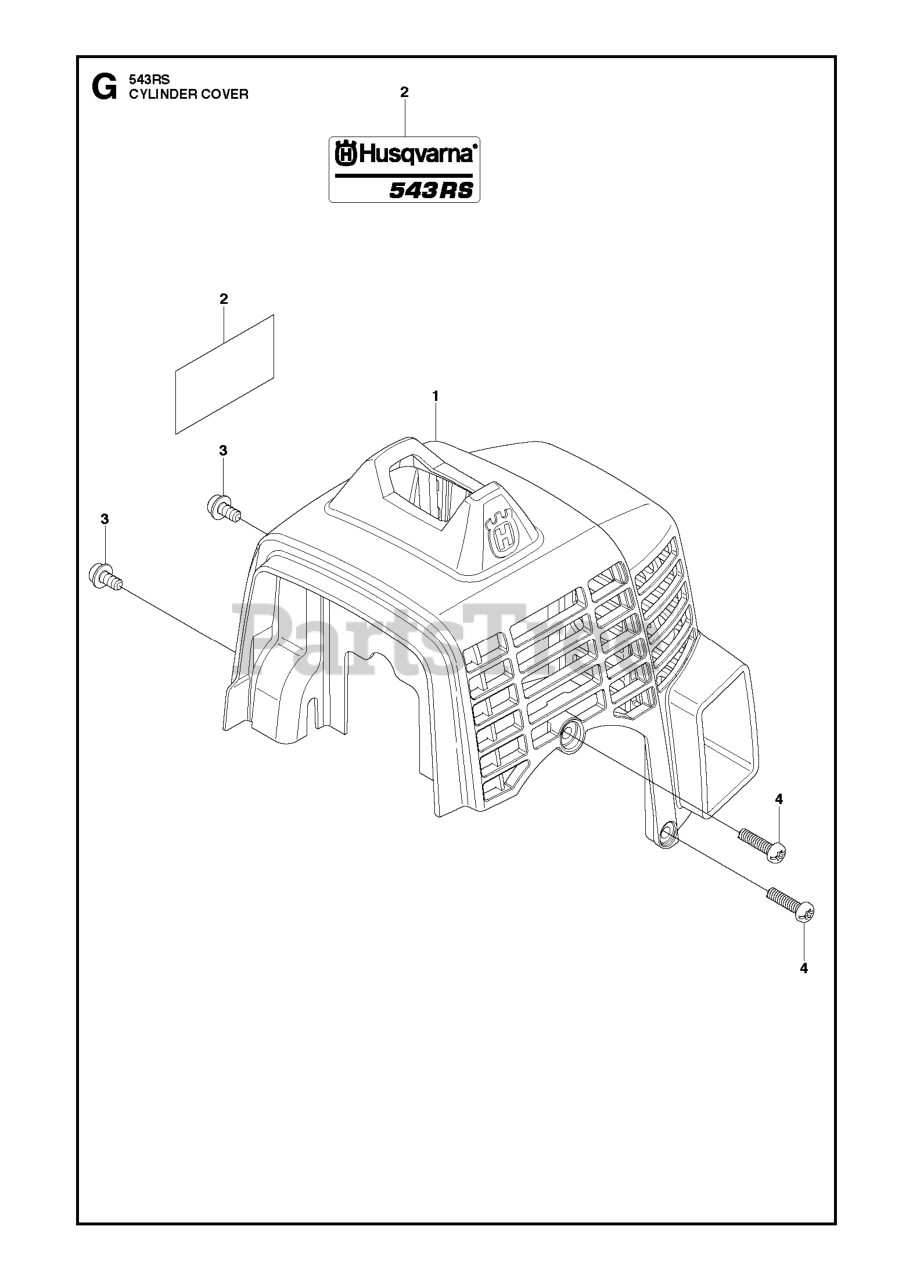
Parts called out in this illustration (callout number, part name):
2	DRAWBAR.LOWER.2PC.18/22
3	APPLIQUE.SUBASM.GT.HUSQ.II
5	DASH.UPP.GT2.DUAL.RD.PTO.MCHOK
14	HOOD.ASM.HUSQVARNA.GT.TEX.ORAN
15	LENS.HEADLIGHT.LH.GTII.2011
18	GRILLE.SUBSTRATE.2011.
25	LENS.HEADLIGHT.RH.GTII.2011
36	SCREW 5/16"
37	FENDER.TLT.FS.W/CPH/FW/RSF.668
58	DRAWBAR UPPER 2PC SMALL FENDER
68	Screw 5/16-18 x 1/2 Hex, Self Tapping 5/16-18 x 1/2
125	CLIP.FUEL.LINE
130	SCREW.#10 X 0.750.BOS
137	BUMPER DASH
146	BOLT.RDHD.SHT.SQNK.3/8-16X5/8
150	AIR.DUCT.GTV.BLACK
151	BRACKET.PIVOT.HOOD.GT.HUSQ.II
152	SHIELD.BROWNING.PNT.GT.V2
159	SCREW, 3/8-16X3/4
161	WINDOW.FUEL.LT.HUSQ.TEX.498
162	SCREW.HI-LO.CONSOLE
165	SUPPORT.TANK.REAR.B/TE
175	PLATE.CROSSMEMBER.HUSQ
176	SCREW.#10-24X5/8.RN.QU
177	BUSHING STEERING
180	CHASSIS.TEX.BOLTED
182	DASH.LOWER.COMMON.12V.ADAPTOR
183	BOLT.5/16-18X1-1/4 FULL THD
189	SCREW
191	INSERT.REFLECTIVE.RH.HUSQ.GTII
194	NUT LOCK HEX FLANGE 5/16-18
199	PLATE.DECK.LIFT.HUSQ.LT
202	VENT.SIDE.RH.GT.HUSQ.II.
203	VENT.SIDE.LH.GT.HUSQ.II.498
204	VENT.TOP.HUSQ.GT2
205	SIDE.TRIM.RH.GT.HUSQ.II
206	SIDE.TRIM.LH.GT.HUSQ.II.GRAY
207	BEZEL LIGHT.RH.GT.II.MYLAR
208	BEZEL LIGHT.LH.GT.II.MYLAR
214	CLIP.RETAINER.TINNER.
217	ROD.PIVOT.HOOD
228	STUD.FASTNER.W/ANTI-ROTATE
235	SPACER FENDER
236	NUT.CENTERLOCK.5/16-
282	CLIP.RETAINER.CONSOLE.LT.HUSQ
283	CONSOLE.DECK.LIFT.R.SDFL.HUSQ
284	CONCOLE.CNTRL.PDL.HUSQ.LT.498
285	CONSOLE INSERT RH
286	CONSOLE.INSRT.LH.HUSQ.LT.BLACK
287	SCREW 1/4X20
297	INSERT.REFLECTIVE.LH.HUSQ.GTII
306	NUT LOCK FLG 3/8-16 UNC
335	COVER.LOWER.DASH.RH.BLACK
336	COVER-LH.LOWER.DASH.GT2.BLACK
350	CLIP.X-MAS.TREE
375	BUMPER CLIP-ON. DASH 1"
